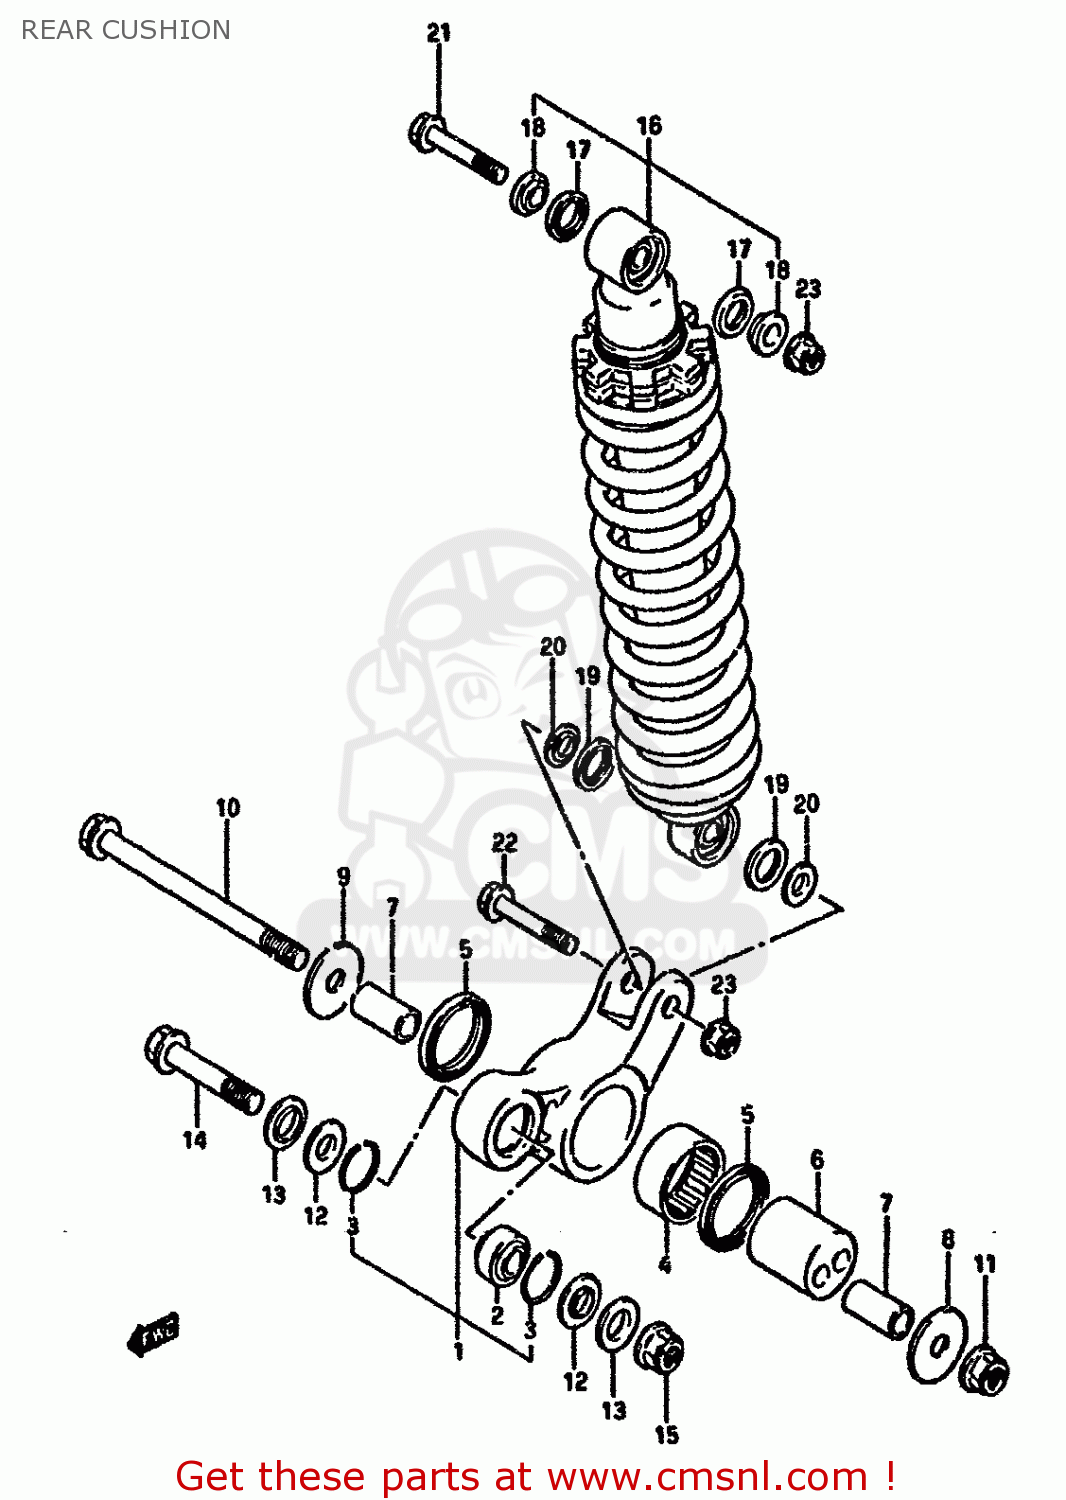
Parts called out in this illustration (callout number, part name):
1	LEVER SET,RR CUSHION
2	BEARING(12X26X16)
3	RING,STOPPER
4	BEARING(37X47X20)
5	SEAL,DUST
6	SPACER,RR SUSPENSION ECCENTRIC
7	SPACER,CUSHION LEVER SHAFT
8	WASHER(12X40X3)
9	WASHER,THRUST,R
10	SHAFT,REAR CUSHION LEVER
11	NUT 12MM
12	SEAL,RR CUSHION ROD DUST
13	SPACER,RR CUSHION ROD
14	BOLT,CUSHION LEVER FR
15	NUT 12MM
16	ABSORBER ASSEMBLY,REAR SHOCK
17	DUST SEAL
18	SPACER
19	SEAL,DUST
20	COLLAR
21	BOLT,REAR SHOCK ABSORBER
22	BOLT(10X48)
23	NUT
